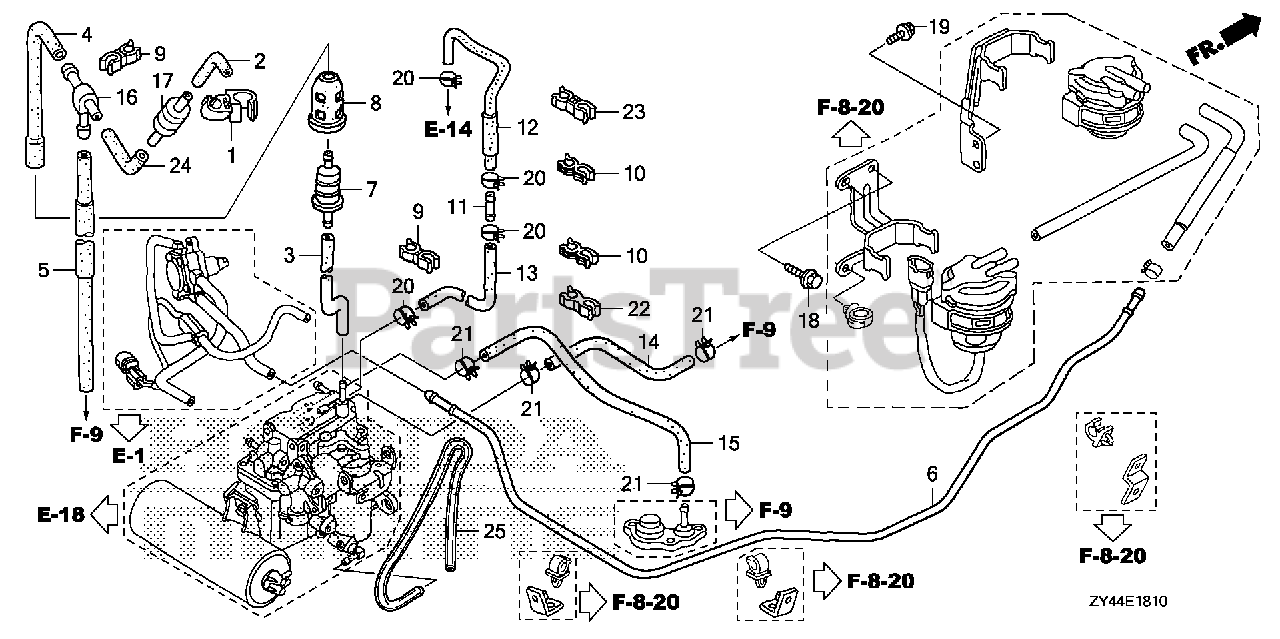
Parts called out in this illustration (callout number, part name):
1	CLAMP, CHECK VALVE
2	TUBE, CHECK VALVE
3	TUBE A, AIR VENT
4	TUBE B, AIR VENT
5	TUBE, AIR VENT
6	PIPE, FUEL
7	FILTER, FUEL PUMP
8	SUSPENSION, STRAINER
9	CLAMP, HOSE
10	CLIP, TUBE
11	JOINT, FUEL RETURN
12	HOSE A, PRESSURE REGULATOR RETURN
13	HOSE B, PRESSURE REGULATOR RETURN
14	TUBE, WATER INLET
15	TUBE, WATER OUTLET
17	VALVE, CHECK
18	BOLT, FLANGE (6X10)
19	BOLT, FLANGE (6X14)
20	CLAMP, TUBE (D10.7)
21	CLAMP, TUBE (D10.5)
22	CLIP, WIRE
23	CLAMP, FUEL TUBE
24	BULK HOSE, FUEL (3.5X3000) (3.5X55)
25	BULK HOSE, VINYL (3.5X6.5X8000) (3.5X6.5X600)
